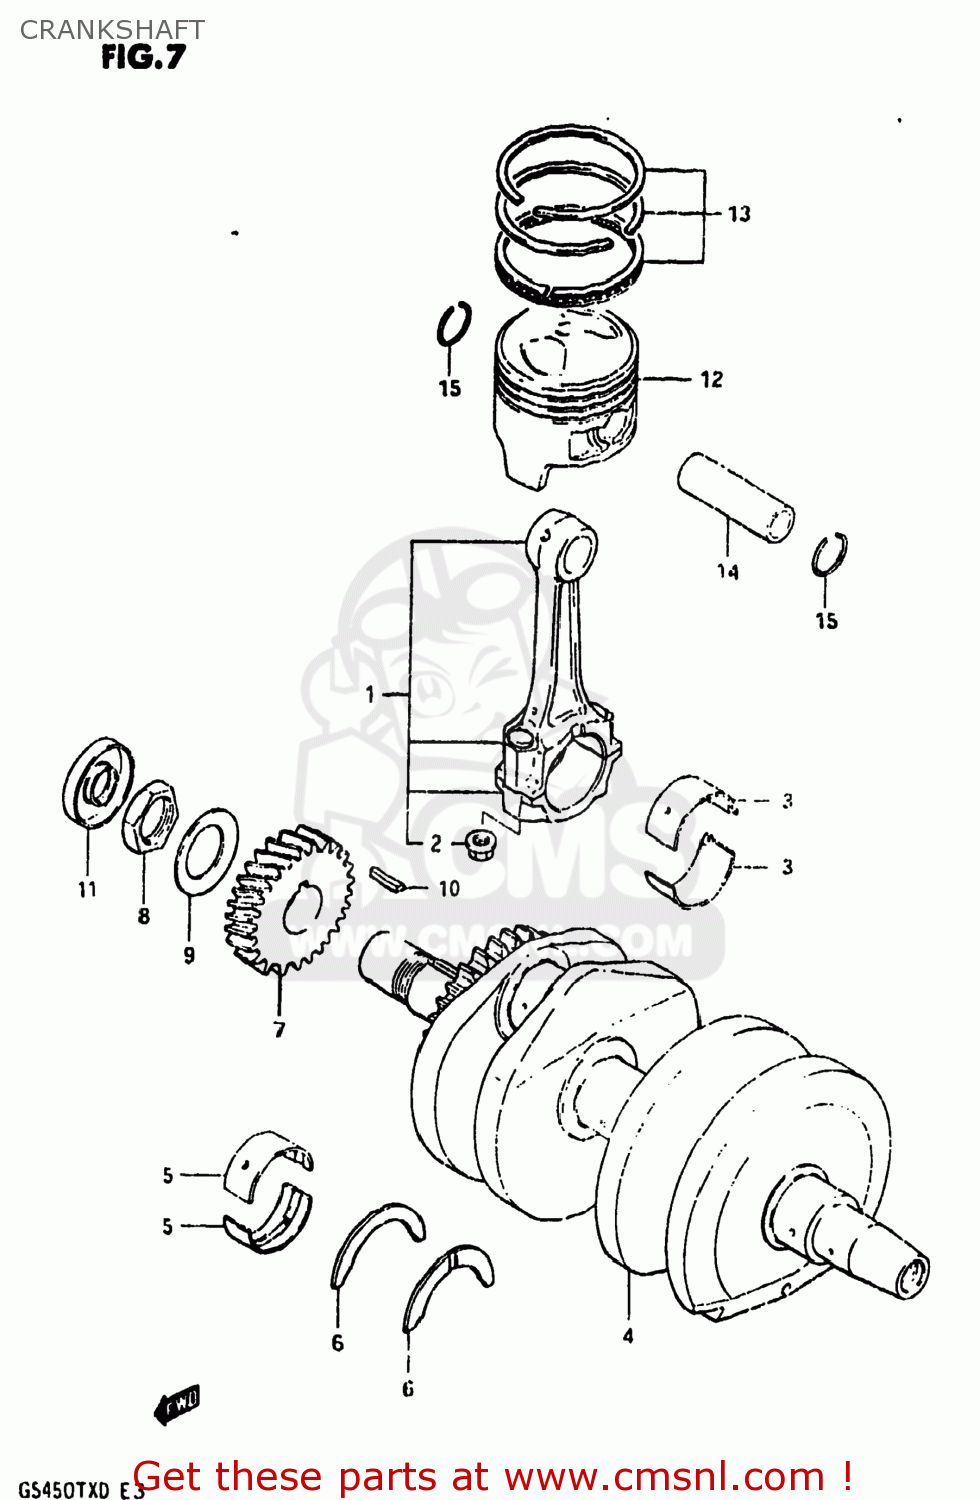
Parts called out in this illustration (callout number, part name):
1	ROD ASSEMBLY,CONNECTING
2	NUT
3	BEARING,CRANK PIN
4	CRANKSHAFT
5	METAL CRANKSHAFT
6	BEARING,CRANK THRUST
7	GEAR,PRIMARY DRIVE NO.28
8	NUT
9	WASHER
10	KEY
11	OIL SEAL
12	PISTON
13	RING SET,PISTON
14	PIN,PISTON (18MM)
15	CIRCLIP
